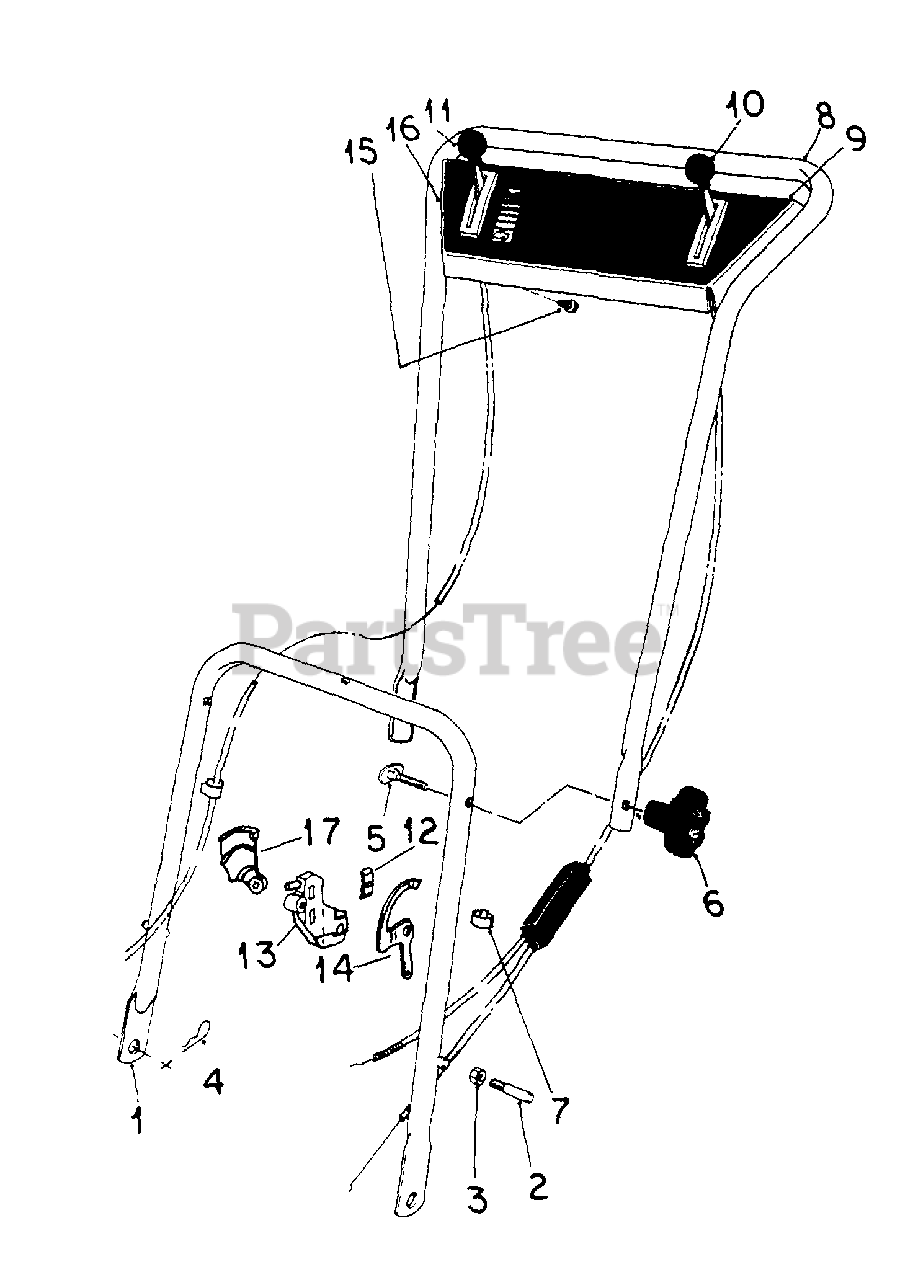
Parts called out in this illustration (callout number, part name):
1	HANDLE, LOWER
2	PIN, HANDLE
3	NUT, 1/4-20 LOCK
4	PIN, HAIR PIN COT
5	BOLT, HANDLE
6	KNOB, HANDLE
8	HANDLE, UPPER
9	PLATE, CONTROL
10	CONTROL, TRACTION
11	CONTROL, THROTTLE
12	CLAMP, CASING
13	BLOCK, CABLE
14	CAM, INTERLOCK
16	PRODUCT GRAPHIC
17	LEVER, INTERLOCK
